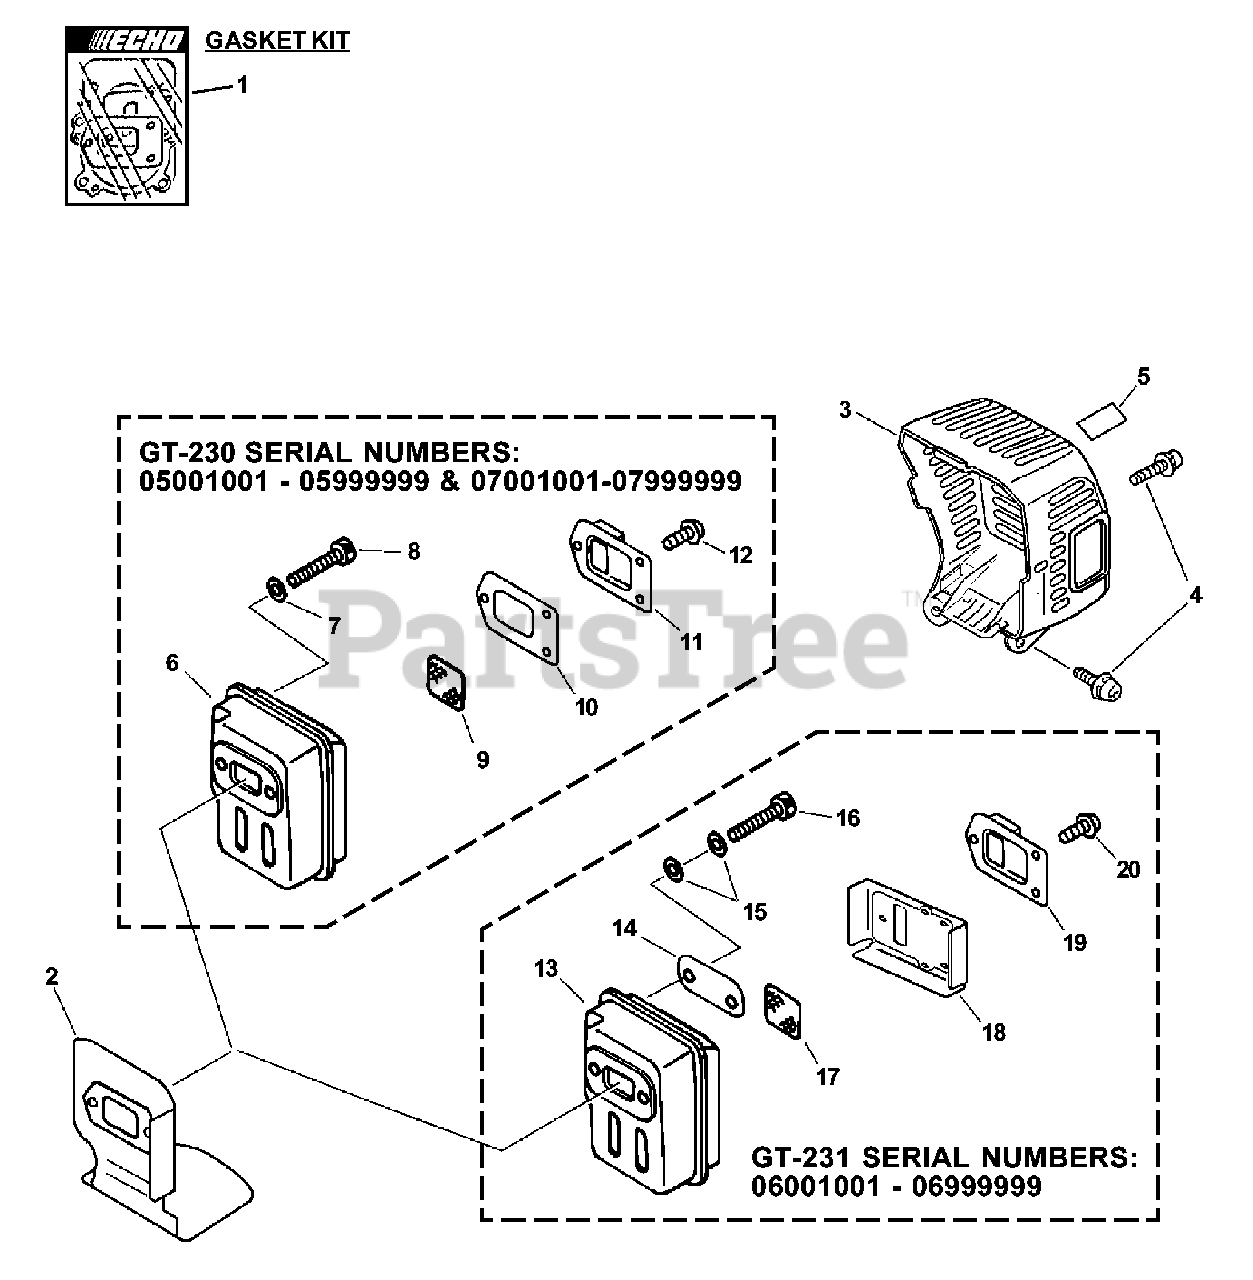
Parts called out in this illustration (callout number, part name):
1	GASKET KIT
2	HEAT SHIELD, EXHAUST
3	COVER, EXHAUST
4	BOLT 5×12
5	LABEL, CAUTION - HOT
6	MUFFLER
7	WASHER, FLAT 5.5×10×0.8
8	BOLT 5×55
9	SCREEN, SPARK ARRESTER
10	GASKET, EXHAUST
11	GUIDE, EXHAUST
12	SCREW 4×10
13	MUFFLER
14	PLATE, EYE
15	CONICAL WASHER
16	BOLT 5×55
17	SCREEN, SPARK ARRESTER
18	GASKET, EXHAUST
19	GUIDE, EXHAUST
20	SCREW 4×10
